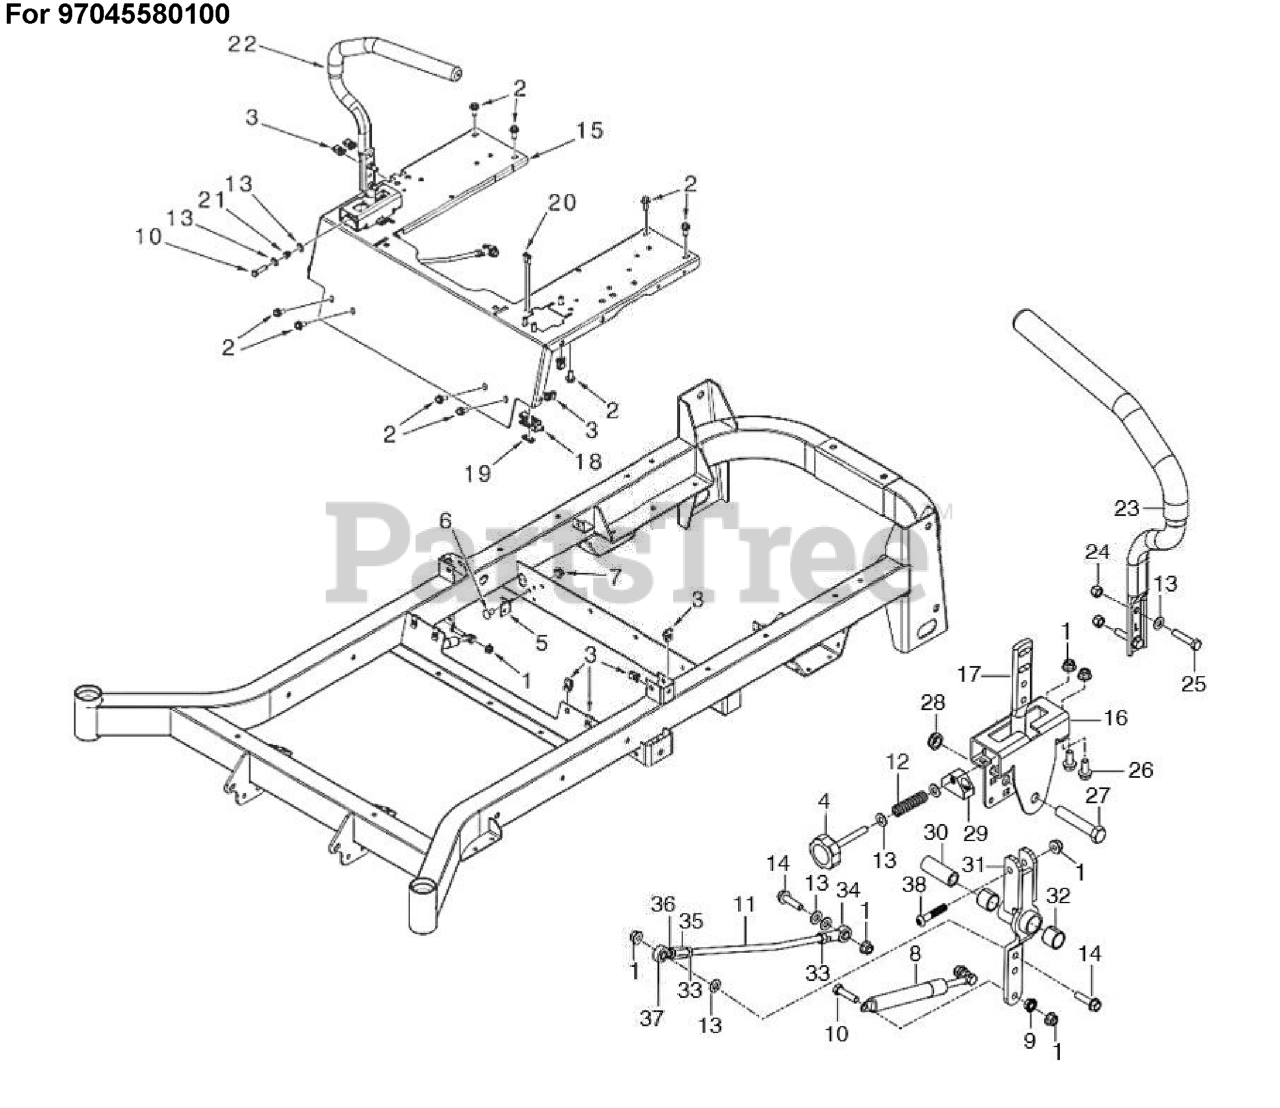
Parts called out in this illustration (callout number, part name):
1	NUT HEXAGON FLANGE 5/16-18 ST
3	U-CLIP 5/16-18 NUT RETAINER
5	BRACKET.DAMPENER.BLACK
9	GSPW Hardware
12	SPRING COMPRESSION 2.0
13	WASHER 11/32 X 11/16 X 14 GA T
15	SUPPORT.PNT.SEAT.CONTROL.ORNG
16	BRACKET.CONTROLS.ZTR.X431
17	LEVER.HANDLE MOUNT
18	SWITCH, INTERLOCK
20	SCR #10-24 X .75 SKT HD BLK
22	TUBE.LEVER.CONTROL.ZTR.RT.428
23	TUBE.LEVER.CONTROL.ZTR.LT.428
26	HHFS 5/16-18 X 3/4
28	NUT 1/2-13 HEX JM NYL
30	SPACER.PIVOT.CONTROL
31	CONTROL.WELDMENT.RZ
32	BEARING.PT.750
34	JOINT.HEIM.FEML.5/16.RH.THREAD
37	ROD.END.MALE.LH.THREAD
38	SCREW 5/16-18 X 1 3/4 BTN-HD
